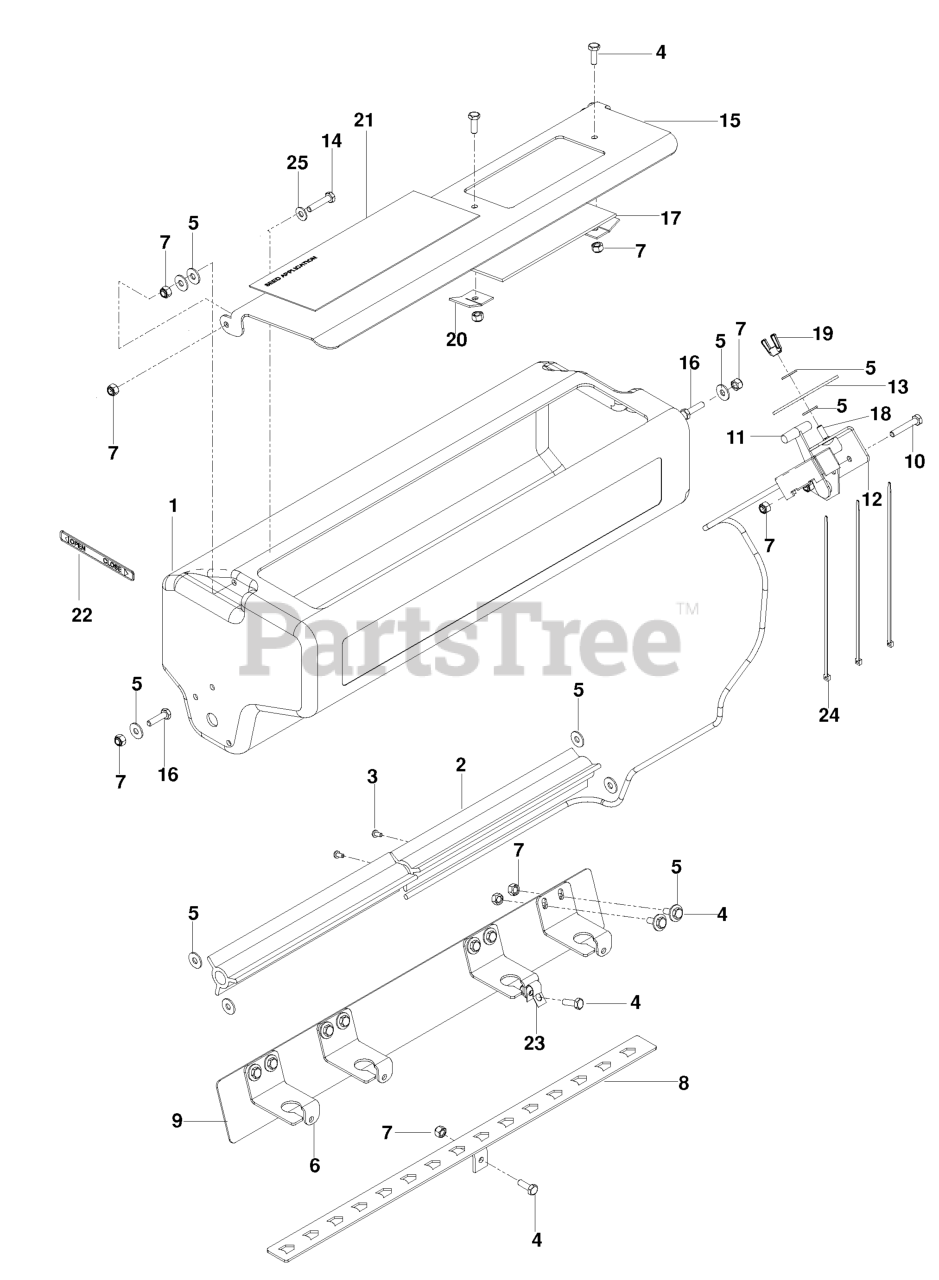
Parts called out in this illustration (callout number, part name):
1	SEED BOX CHARCOAL GREY
3	R/B 108495 SCR SLF TP 8-32X3/8
4	HCS 1/4C X 3/4 HCS
5	WASHER 1/4 FLAT
7	NUT.1/4-20.HEX.NYLOC.ZD
10	SCW 1/4-20 X 1-1/2 HEX
11	CONTROL, PUSH/PULL ASSEMBLY
14	BOLT HEX 1/4 X 1-1/4
15	SEED DOOR ORANGE
16	HCS 1/4 X 1
17	SEED WINDOW
18	RHSNB 1/4C X 3/4
19	WING NUT 1/4
20	WINDOW CLIP
21	DECAL, SEED APPL
22	DECAL, OPEN/CLOSE
23	BRACKET, PUSH/PULL
24	TIE, PLASTIC
25	WASHER 1/4 SAE
